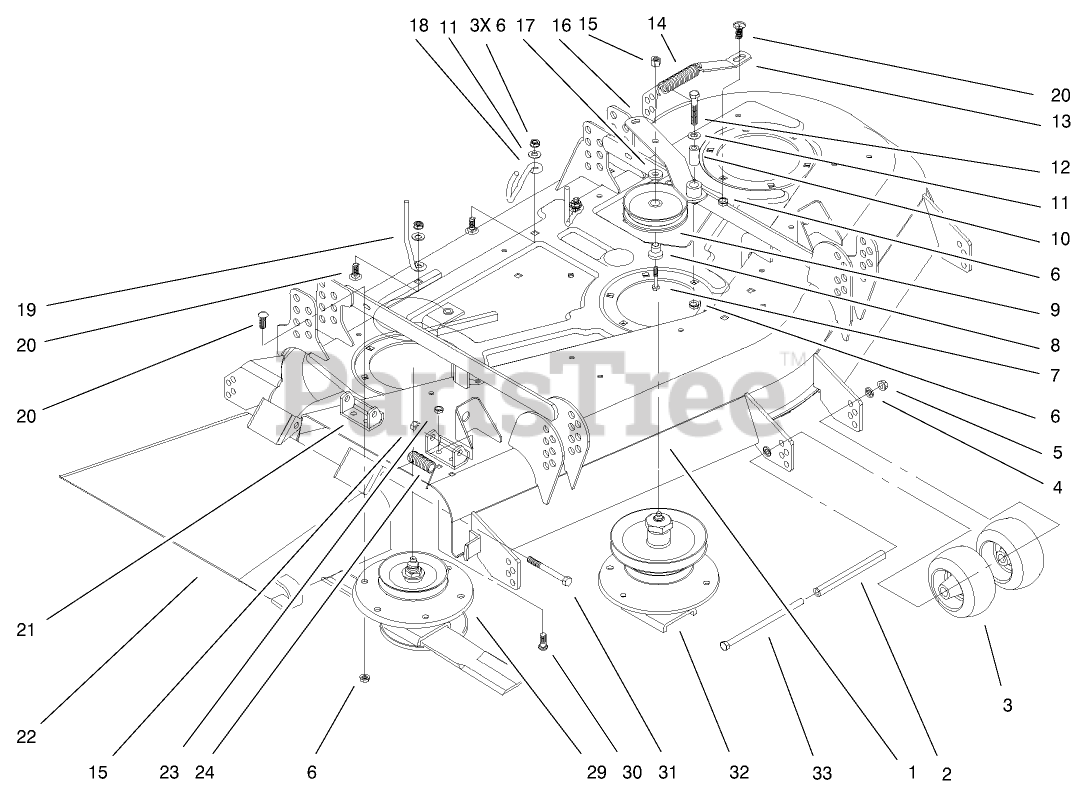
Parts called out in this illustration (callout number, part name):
1	52" DECK W/DECALS
2	SPACER-WHEEL
3	WHEEL-GAGE
4	WASHER-PLAIN
5	NUT-LOCK, NI
6	NUT-HF
7	SCREW-HH
8	BUSHING-PULLEY
9	PULLEY-IDLER
10	SLEEVE
11	WASHER-FLAT
12	SCREW-HH
13	PLATE-SPRING
14	Spring-Extension
15	NUT-HEX
16	IDLER ARM ASM
17	WASHER-FLAT
18	GUIDE-BELT
19	ROD-BELT
20	SCREW-CARR
21	BRACKET-PIVOT
22	Deflector
23	NUT-LOCK, CONE
24	SPRING
29	SPINDLE ASM
30	SCREW-CARR
31	SCREW-HH
32	HOUSING - SPINDLE ASM
33	SCREW-HH
